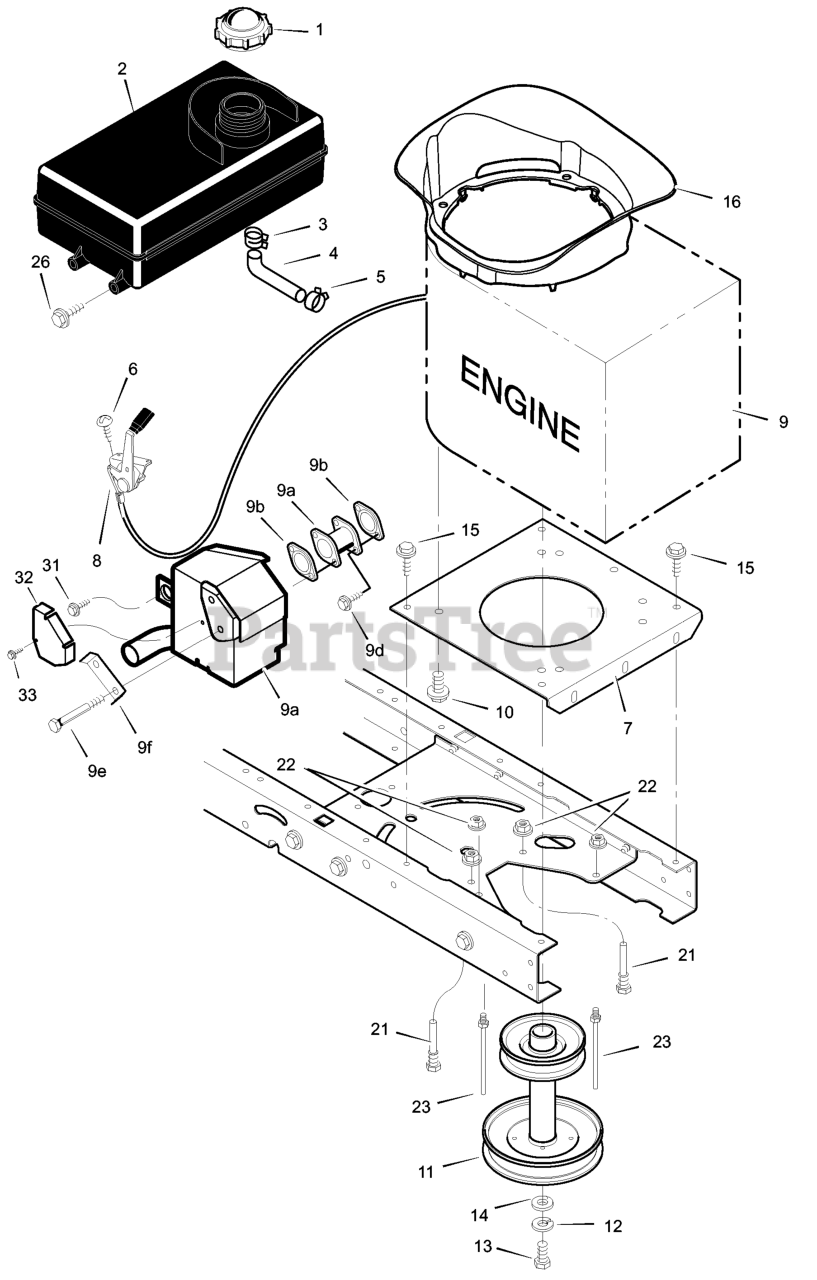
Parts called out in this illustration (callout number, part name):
1	Fuel Cap
2	TANK, Fuel 1.4 Gal.
3	Hose Clamp
4	Fuel Line (Must cut to length)
5	Hose Clamp
7	Plate, Engine
8	Throttle Control
9	Engine
9A	Muffler and Heat Shield
9B	GASKET, Exhaust
9C	Adapter, Muffler
9D	Screw, Adapter
9E	Bolt, Muffler
9F	Lock, Screw
10	Bolt, Engine Mount
11	STACK PULLEY ASSEMBLY
12	Lockwasher
13	Bolt, Hex
21	Guide, Belt
22	Nut, Flange
23	Guide, Belt
32	Shield, Heat
